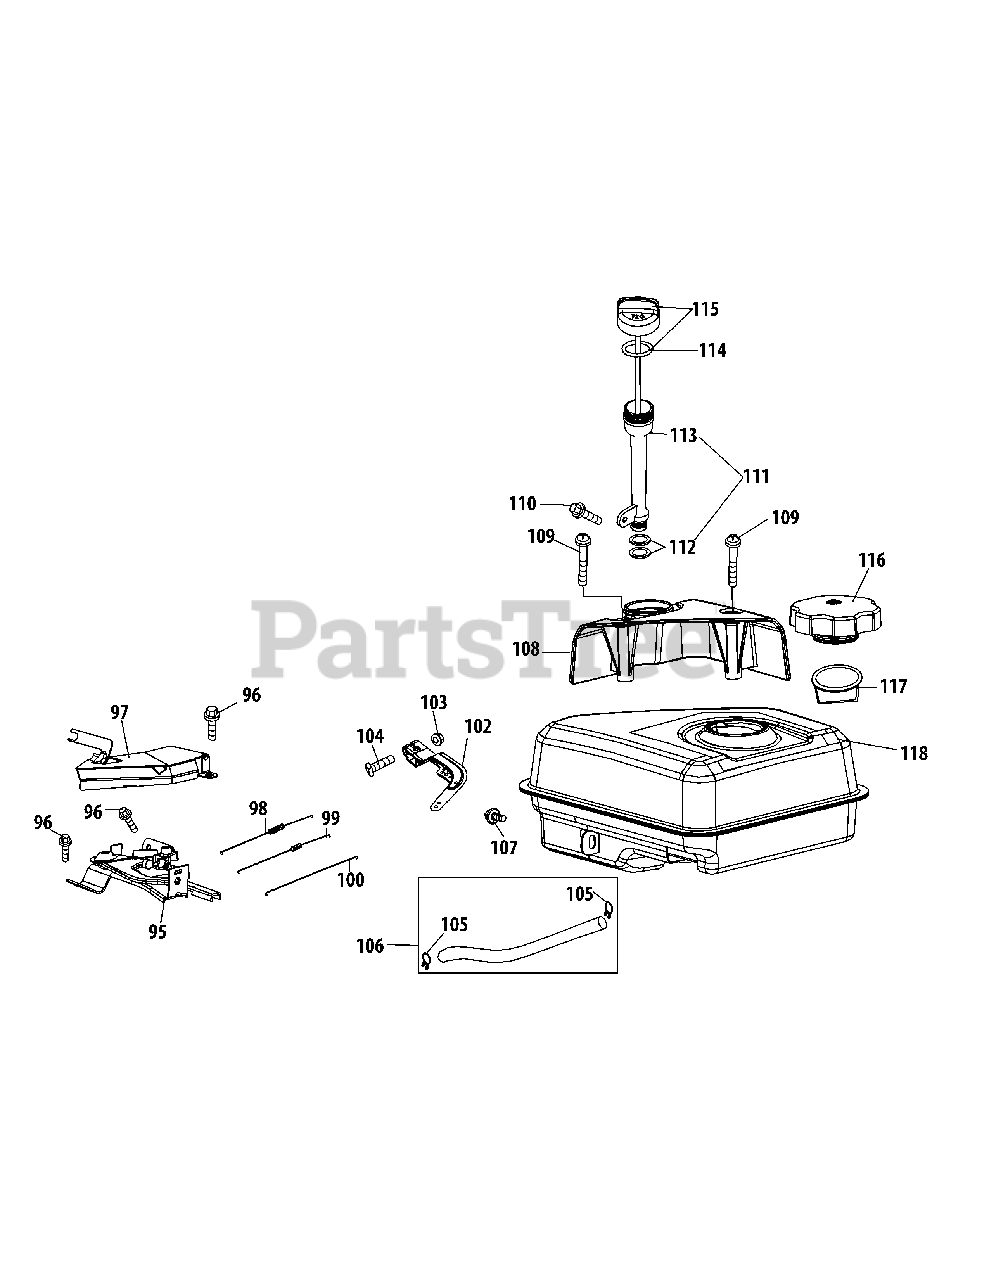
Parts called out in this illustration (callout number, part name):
95	Primer Bracket
96	Bolt M6×12
97	Governor System Shield
98	Governor Spring
99	Throttle Linkage Spring
100	Throttle Linkage
102	Governor Arm
103	Nut M6
104	Governor Arm Bolt
105	Fuel Hose Clamp
106	Fuel Line Kit
107	Bolt M6×12
108	Dipstick Decoration Cover
110	Bolt M6×12
111	Oil Fill Tube Assembly
113	Oil Fill Tube
115	Dipstick Assembly
116	Fuel Cap Assembly
117	Fuel Level Indicator
118	Fuel Tank Assembly
